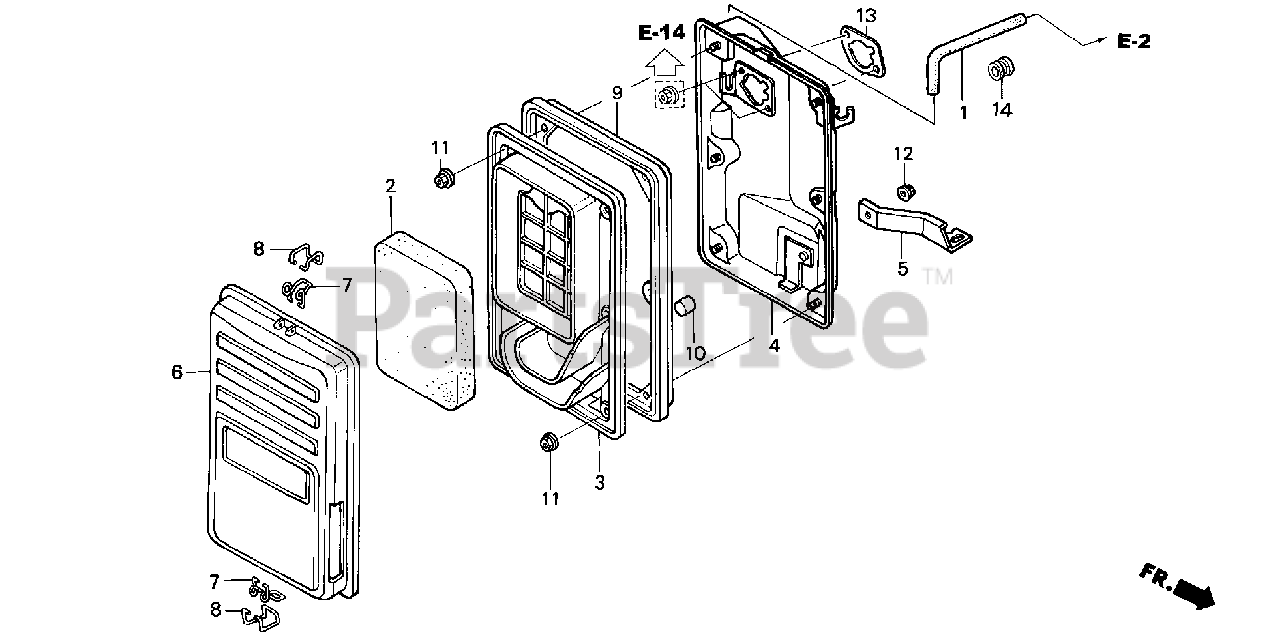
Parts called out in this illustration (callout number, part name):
1	TUBE, BREATHER
2	ELEMENT, AIR CLEANER
3	SEPARATOR, AIR CLEANER
4	HOUSING, AIR CLEANER
5	STAY, AIR CLEANER
6	COVER, AIR CLEANER
7	CLIP A, AIR CLEANER WIRE
8	CLIP B, AIR CLEANER WIRE
9	SEAL, AIR CLEANER
10	FILTER, DRAIN TUBE
11	NUT, FLANGE (5MM)
12	NUT, FLANGE (6MM)
13	GASKET, AIR CLEANER
14	GROMMET, FENDER
